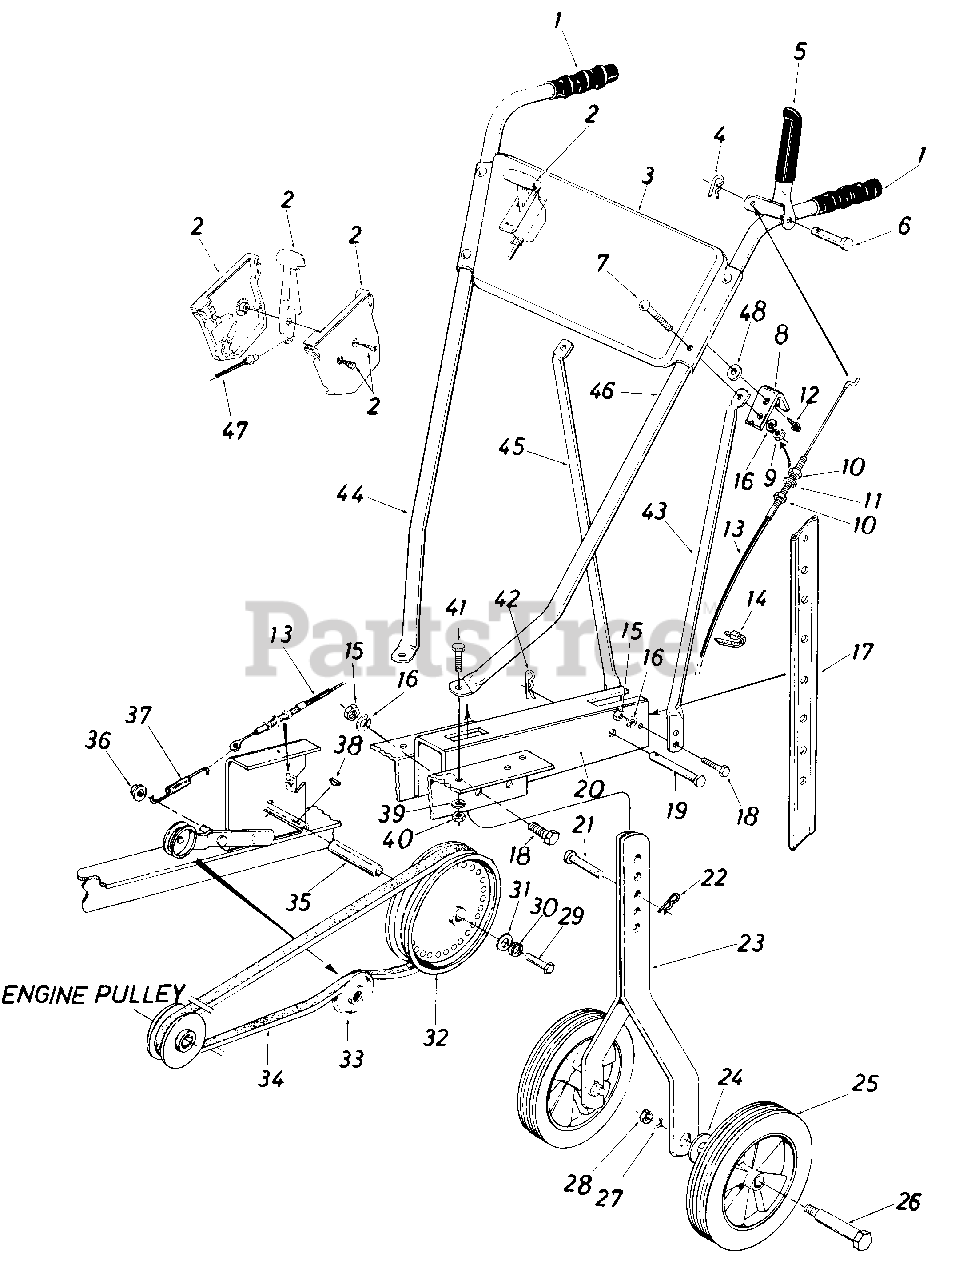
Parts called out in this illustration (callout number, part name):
2	Throttle Control Box
3	Handle Panel
4	Int. Cotter Pin
5	Clutch Grip Ass'y.
6	Clevis Pin
7	Carriage Bolt 5/16-18 x 1.75" Lg.
8	Cable Support Brk't.
9	Hex Nut 5/16-18 Thd.
10	Hex Jam Nut 5/16-24 Thd.
11	L-Wash. 5/16" I.D.
12	Hex Wash. Hd. Self-Tap Scr. 1/4-20 x 50" Lg.
13	Clutch Control Cable
14	Cable Tie
15	Hex Nut 5/16-18 Thd.
16	L-Wash. 5/16" I.D.
17	Depth Bar
18	Hex Bolt 5/16-18 x .75" Lg.
19	Clevis Pin 1/2" Dia. x 2.50" Lg.
20	Tailpiece Ass'y.
21	Clevis Pin 3/8 Dia. x 2.50" Lg.
22	Hairpin Cotter
23	Wheel Bracket Ass'y.
24	Belleville Wash. 1/2" I.D.
25	Wheel Ass'y. 9 x 1.75
26	Shoulder Bolt
27	L-Wash. 1/2" I.D.
28	Hex Nut 1/2-20 Thd.
29	Hex Bolt 1/4-28 x .75" Lg.
30	L-Wash. 1/4" I.D.
31	Fl-Wash. .25" I.D. x .930" O.D.
32	Pulley 6.00" O.D.
33	Idler Pulley
34	"V"-Belt 1/2" Pitch x 39" Lg.
35	Spacer
36	Cap Speed Nut
37	Extension Spring
38	Hi-Pro Key
39	L-Wash. 5/16" I.D.
40	Hex Nut 5/16-18 Thd.
41	Hex Bolt 5/16-18 x .75" Lg.
42	Hairpin Cotter
43	Handle Support Bracket L.H.
44	Handle Bar R.H.
45	Handle Support Bracket R.H.
46	Handle Bar L.H.
47	Throttle Control Cable 35"
48	Fl-Wash. .281" I.D. x .50" O.D.
